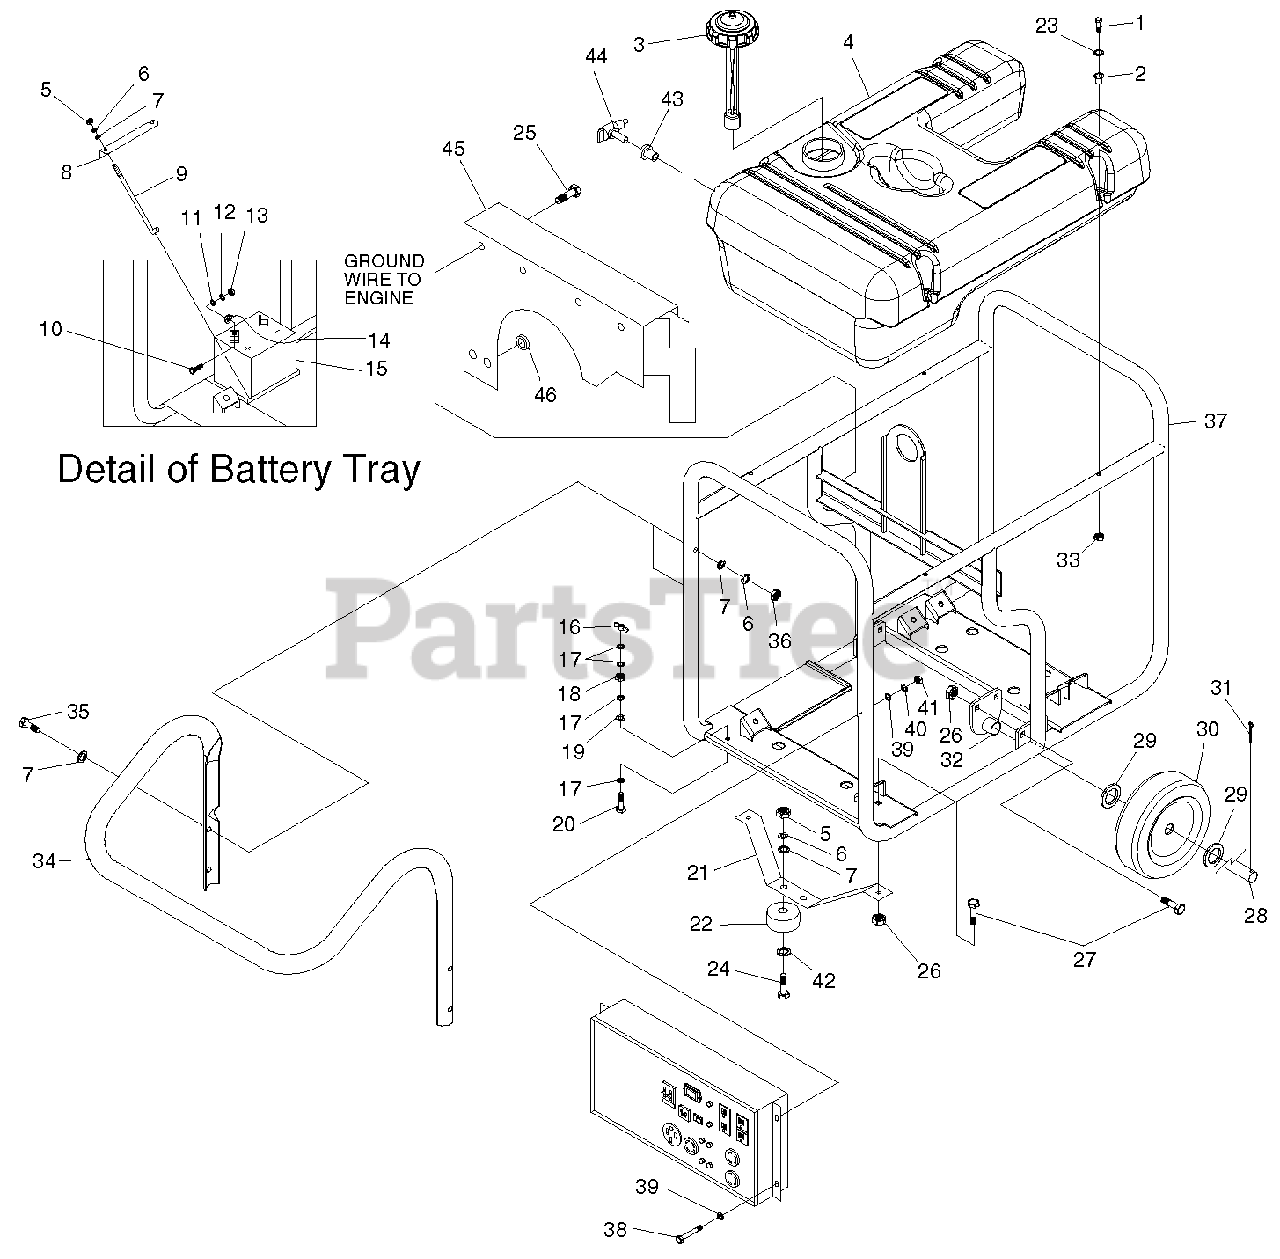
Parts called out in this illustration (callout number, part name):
1	SCREW HHC M6-1.0 X 55
2	RUBBER TANK MOUNT
3	CAP, FUEL WITH GAUGE & VENT
4	KIT, FUEL TANK
5	NUT HEX M8-1.25
6	WASHER LOCK M8-5/16
7	WASHER FLAT 5/16
8	BRACKET BATTERY
9	BOLT,BATTERY J-BOLT
10	SCREW HHC 1/4-20 X 3/4 G5
11	WASHER FLAT 1/4
12	WASHER LOCK M6-1/4
13	NUT HEX 1/4-20
14	BATTERY CABLE, RED
15	BATTERY U1
16	NUT WING 5/16-18 BRASS
17	WASHER FLAT 5/16 BRASS
18	NUT HEX 5/16-18 BRASS
19	5/16 SPECIAL L/WASH
20	SCREW HHC 5/16-18 X 1.5 BRASS
21	BRACKET FRONT FOOT
22	VIB MOUNT
23	WASHER FLAT .25ID X 1"OD
24	SCREW HHC M8-1.25 X 30
25	SCREW HHTT M6-1.0 X 12
26	NUT LOCK FL 3/8-16
27	BOLT CARR 3/8-16 X 1
28	AXLE, 3/4"DIA X 27.25"
29	WASHER FLAT 3/4
30	10" PNEUM WHEEL 3/4" AXLE
31	PIN COTTER 1/8 X 1-1/4
32	BRACKET, WHEEL SPACER
33	NUT FLANGE M6-1.0 NYLOK
35	SCREW HHC 5/16-18 X 2-1/2 G5
36	NUT LOCK HEX 5/16-18 NYLON INSERT
37	FRAME
38	SCREW HHC M5-0.8 X 45 G8.8
39	WASHER FLAT M5
40	WASHER LOCK M5
41	NUT HEX M5-0.8
42	WASHER FLAT 1"
43	BUSHING TANK DEXTOR
44	VALVE, PLASTIC TANK
45	AIR DEFLECTOR
46	GROMMET .75 X .06 X .50
47	CLAMP HOSE BAND 1/4
48	HOSE 1/4 ID
49	BOOT BATTERY CABLE
50	BOOT STARTER CABLE
